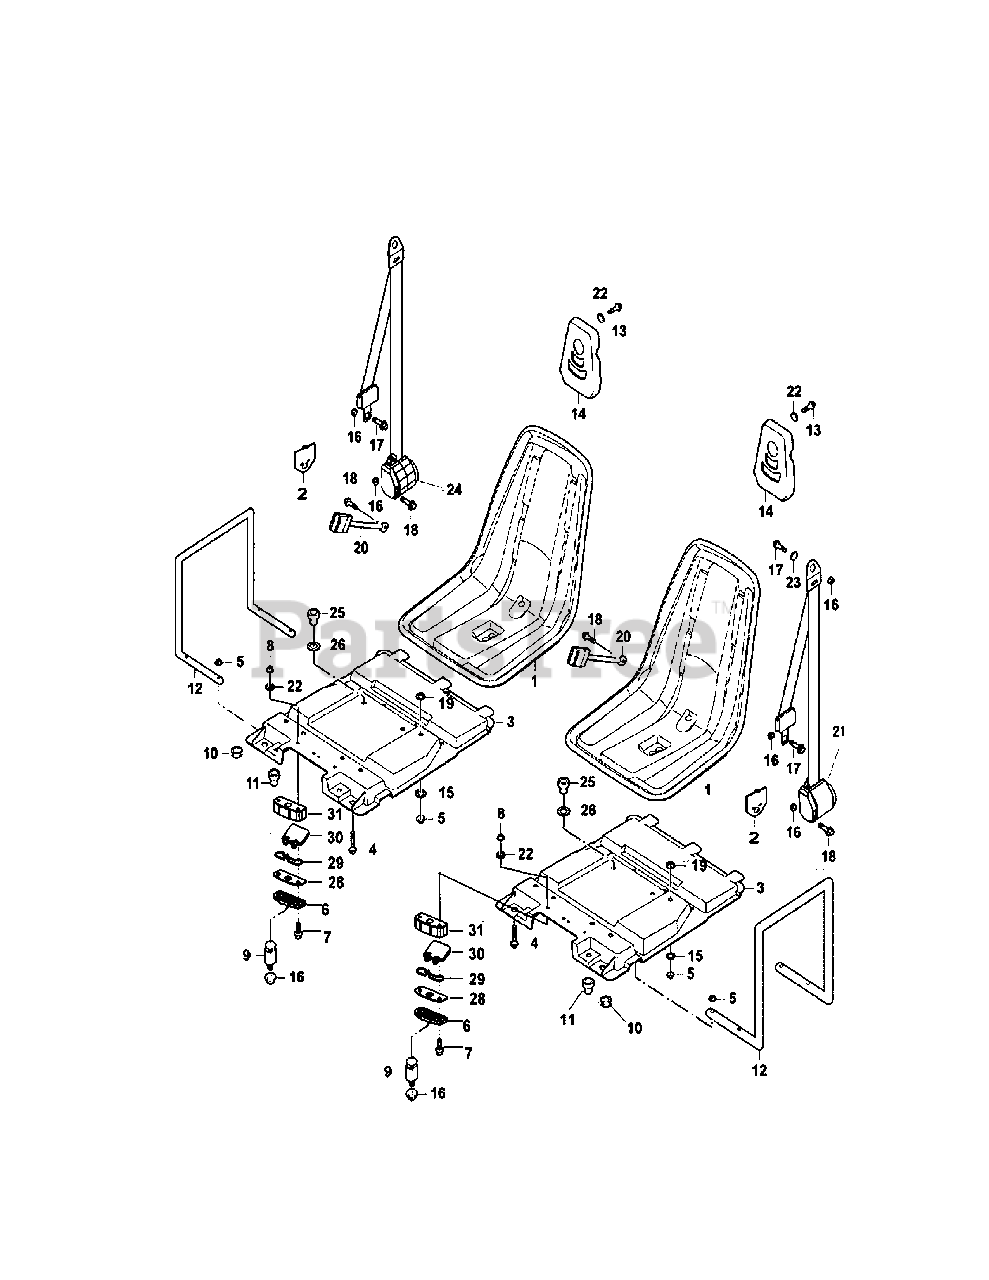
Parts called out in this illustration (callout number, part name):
1	Seat Assy
2	Safty Belt Placing Plate
3	Seat Mounting Board
4	Hexagon Flange Bolt M8×30
5	Hexagon Flange Nut M8
6	Seat Locker Cover
7	Hexagon flange bolt M6×40
8	Hexagon Flange Nut M6
9	Locker Bracket, Seat
10	Shock Absorber Cushion III
11	Shock Absorber Cushion VII
12	Side Armrest
13	Hexagon Flange Bolt M6×25
14	Head Rest
15	Cushion 8.5×28×1.5
16	Hexagon flange nut M10×1.25
17	Hexagon Flange Step Bolt M10×1.25×20-14×5
18	Hexagon flange bolt M10×1.25×20
19	Cushion 10.5×25×3
20	Safety Belt Buckle
21	Safety Belt Assy (L)
22	Washer6×18×1.6
23	Cushion 10×19×5
24	Safety Belt Assy (R)
25	Collar Bushing 8×25×36×7
26	Cushion 8.5×22×1.2
27	Cushion 10.5×25×3
28	Seat Spring Pressure-plate
29	Seat Locker Spring
30	Seat Locker Lever
31	Seat Locker Body
